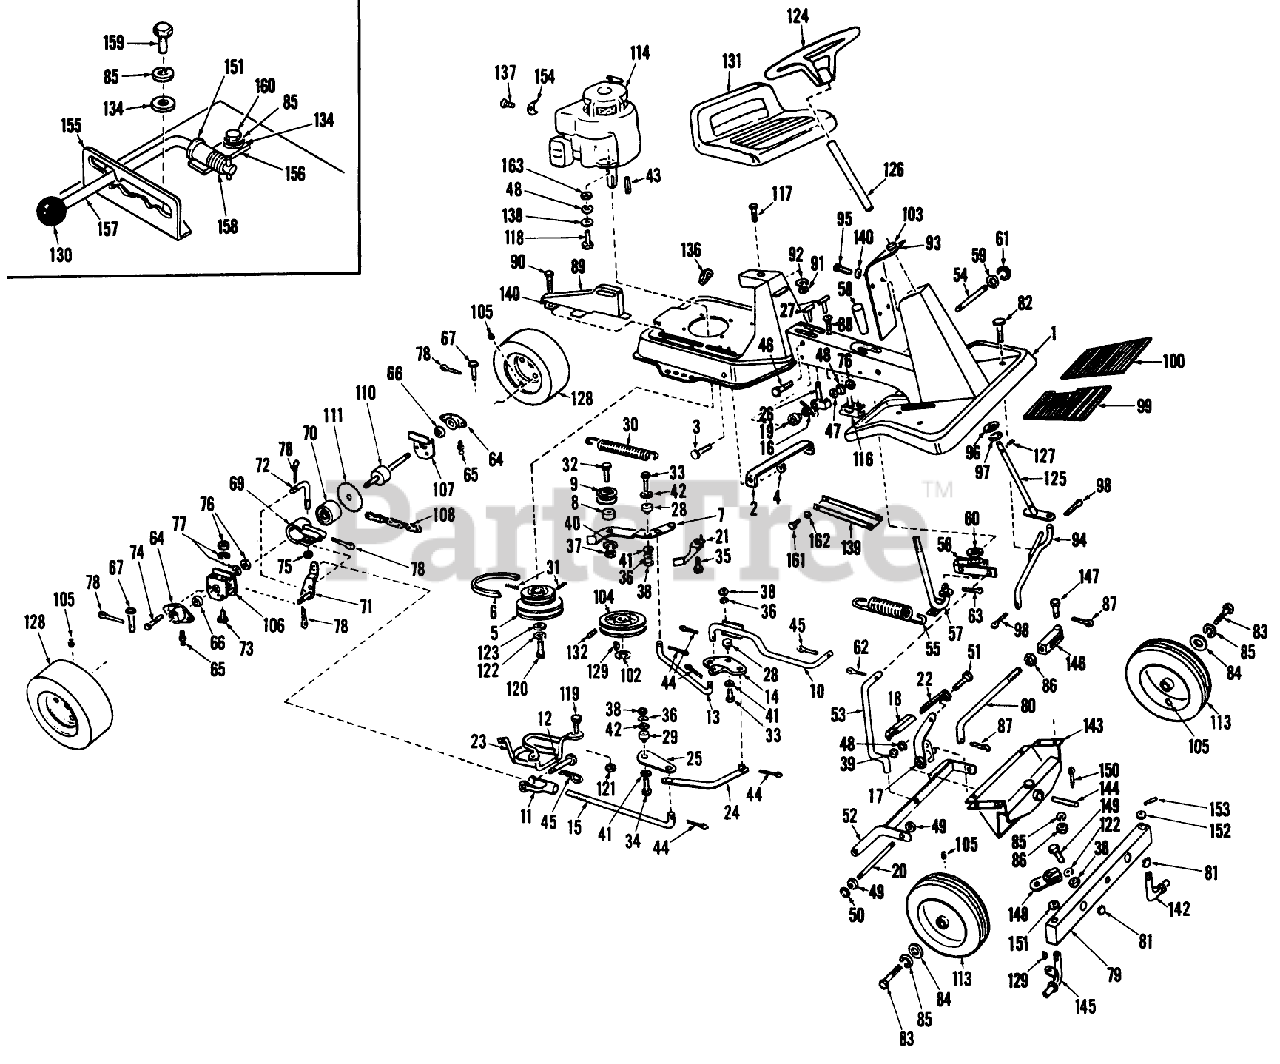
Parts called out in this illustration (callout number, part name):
1	Frame Assembly
2	Brace-Engine Base
3	5/16-18 Wafer Hd. Bolt-Plated
4	5/16-18 Hex Jamnut-Plated
5	Engle Pulley
6	V-Belt-Traction Drive
7	Idler Arm
9	Idler Pulley
10	Brake Rod Assembly
12	Clevis Pin
13	Link-Idler Arm
14	Bellcrank-Plate
15	Clevis Link
16	Torsion Spring
17	Brake Pedal Assembly
18	Brake Pedal Pad
19	Pivot Bushing
20	Pivot Shaft
21	Belt Guard
22	Brake Pedal-Extension
23	Belt Guide Assembly
24	Lever Assembly
25	Pivot Link
26	Latch Handle-Brake
27	Knob-Brake and Throttle
28	Pivot Bushing
29	Pivot Bushing
31	5/16-18 x 5/16 Socket Hd. Setscrew
32	1/2-13 x 1 1/2 Hex. Hd. Capscrew-Plated
33	3/8-16 x 1 1/2 Hex Hd. Capscrew-Plated
34	3/8-16 x 1 1/4 Hex Hd. Capscrew-Plated
35	5/16-18 x 1/2 Whiz Lock Screw-Plated
36	3/8 Lockwasher-Plated
37	1/2-13 Hex Nut-Plated
38	3/8-16 Hex Nut-Plated
39	5/16-18 Hex Nut-Plated
40	1/2 Lockwasher-Plated
42	3/8 Flat Washer-Plated
43	1/4 x 1/4 x 2 Key
44	1/8 x 3/4 Cotter Pin-Plated
45	Spring Clip
46	5/16-18 x 1 1/4 Hex Hd. Capscrew-Plated
47	5/16 Flat Washer-Plated
48	5/16 Lockwasher-Plated
49	5/8 SAE Flat Washer-Plated
50	Retaining Ring
51	5/16-18 Wafer Hd. Bolt-Plated
52	Hanger Arm Assembly
53	Lift Link
54	Lift Pivot Shaft
55	Mower Belt Tension Spring
56	Bracket Assembly-Lift Handle
57	Lift Handle Assembly
60	1/2 SAE Flat Washer-Plated
61	Retaining Ring
62	1/8 x 3/4 Cotter Pin-Plated
63	1/8 x 1 Cotter Pin-Plated
64	Clamp Plate
65	Grease Fitting
66	Bearing
67	Clevis Pin
69	Brake Lining Assembly
70	Brake Drum
71	Brake Lever and Shaft Assembly
72	Brake Adjusting Link
73	5/16-18 Wafer Hd. Bolt-Plated
74	5/16-18 x 3/4 Hex Hd. Capscrew-Plated
75	5/16-18 Hex Locknut-Plated
76	5/16-18 Hex Nut-Plated
77	5/16 Lockwasher-Plated
78	1/8 x 3/4 Cotter Pin-Plated
79	Front Axle Assembly
80	Steering Tie Rod
81	Plug Button
82	5/16-18 Wafer Hd. Bolt-Plated
83	5/16-18 x 7/8 Hex Hd. Capscrew-Nylock
85	5/16 Lockwasher-Plated
86	5/16 Hex Nut-Plated
87	1/8 x 3/4 Cotter Pin-Plated
88	8-32 x 1/2 Hex Hd. Capscrew-Plated
89	Chain Guard Assembly
90	1/4-20 x 1/2 Hex Hd. Capscrew-Plated
91	1/2-13 Hex Nut-Plated
92	1/2 Lockwasher-Plated
93	Steering Panel Assembly
94	Steering Link
95	1/4-20 x 3/4 Hex Hd. Capscrew
97	Retaining Ring
98	1/8 x 3/4 Cotter Pin-Plated
99	Foot Pad-R.H.
100	Foot Pad-L.H.
102	Retaining Ring
103	Flanged Bushing
104	Input Pulley
105	Valve Cap
106	Clamp and Sleeve Assembly
107	Bearing Clamp Bracket
110	Differential
111	Sprocket
113	Wheel Tire Assembly
114	Engine-5 H.P. B S Model 13092, Type 0207-01
116	Throttle Clamp Cable Ass-y.
117	1/2-13 x 1 Short Neck Carriage Bolt
118	5/16-18 x 1 1/2 Hex Hd. Capscrew-Plated
119	5/16-18 x 3/4 Hex Hd. Capscrew-Plated
120	3/8-24 x 3/4 Nylock Capscrew
121	5/16-18 Hex Nut-Plated
122	3/8 Lockwasher
124	Steering Wheel
125	Steering Shaft Assembly
126	Steering Column Tube
127	1/4 x 1 Roll Pin
128	Wheel and Tire Assembly
129	3/16 x 3/4 Woodruff Key
131	Seat Assembly
132	1/4-20 x 1/4 Socket Setscrew
134	5/16 Flat Washer
136	Cable Clamp
137	No. 10-32 x 5/8 Hex Screw
138	5/16 Flatwasher
139	Channel Brace Assembly
140	1/4 Spring Lockwasher-Pl.
141	1/4-20 x 1/2 Hex. Capscrew-Pl.
142	Spindle Ass-y.-L.H.
143	Bracket-Foot Rest Assembly
144	Pivot Pin
145	Spindle Ass-y.-R.H.
147	Clevis Pin
148	Steering Arm
149	3/8-16 x 2 Hex. Capscrew
150	3/16 x 1 3/4 Cotter Pin-Pl.
151	3/8 SAE Flatwasher-Pl.
152	5/8 SAE Flatwasher-Pl.
153	3/16 x 1 Roll Pin
154	Throttle Clamp
155	Shift Index Plate
156	Shift Rod Plate Assembly
157	Shift rod
159	Self Tapping Screw
160	5/16-24 x 5/8 Hex Hd. Capscrew
161	1/4-20 x 1/2 Cap Screw
162	1/4 Lockwasher
163	5/16 x 18 Hex. Cone Locknut
